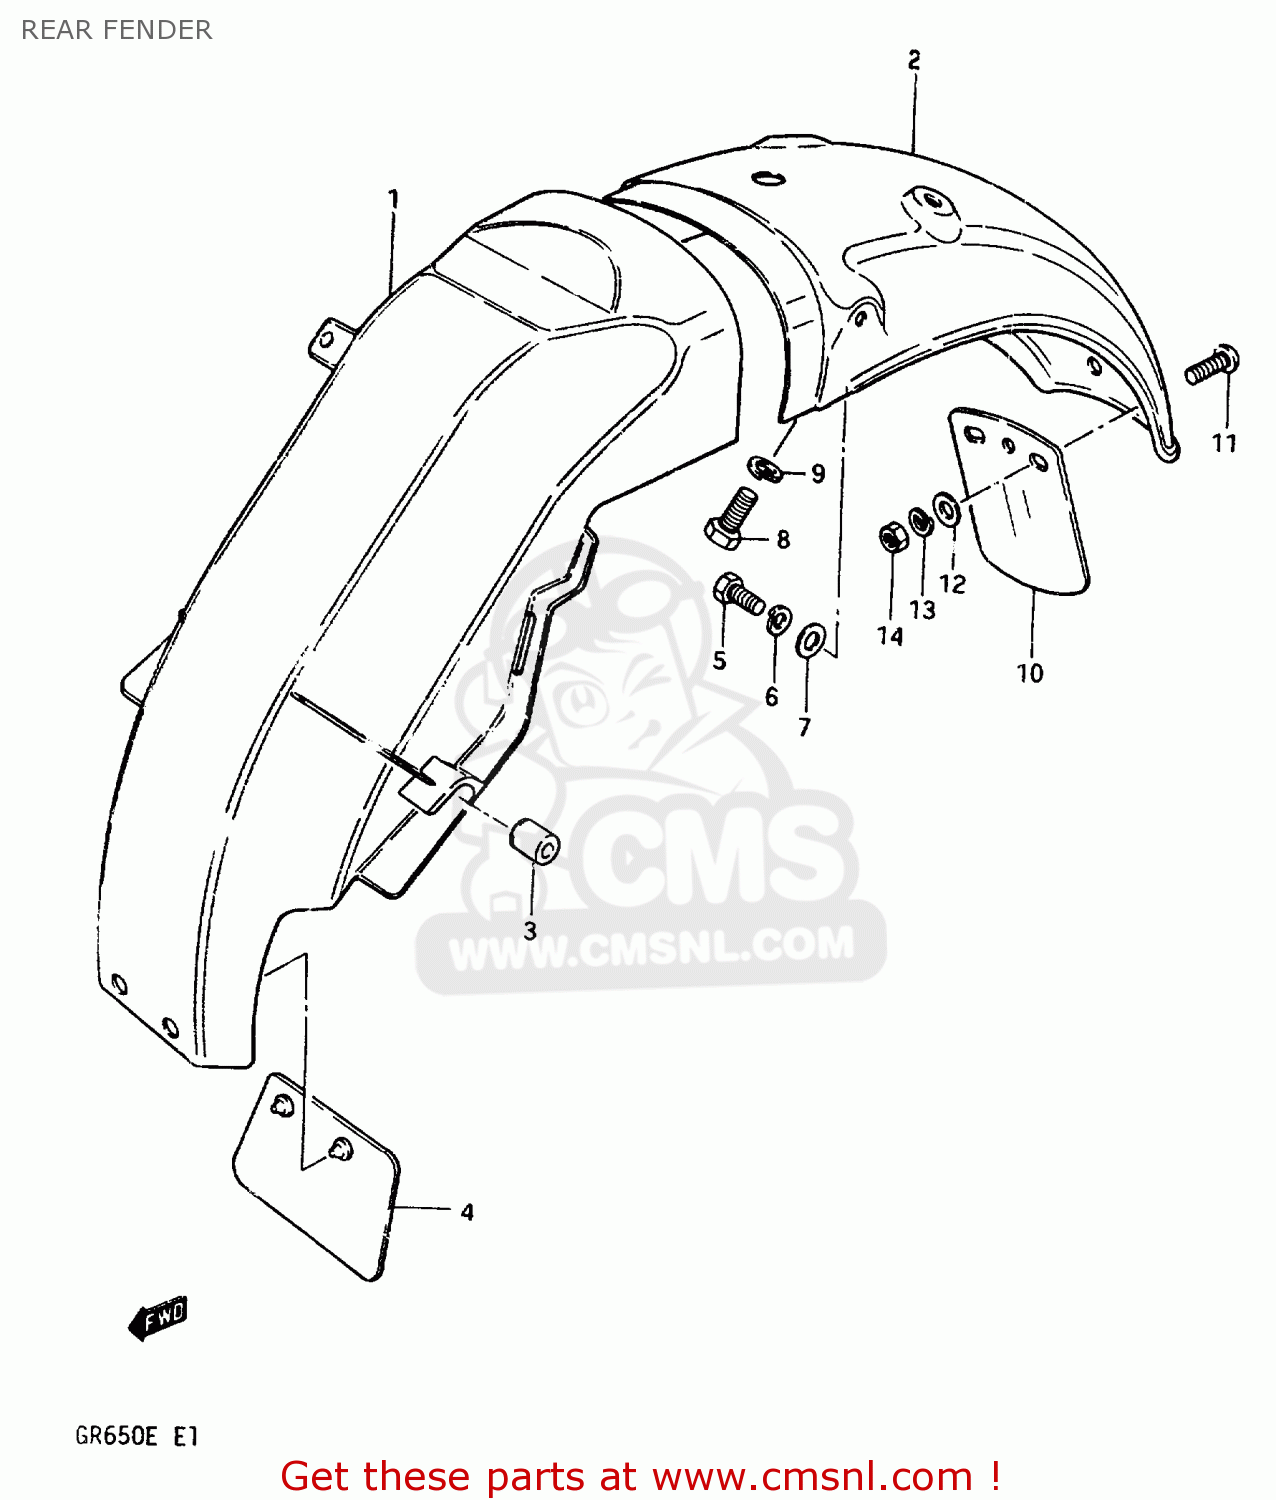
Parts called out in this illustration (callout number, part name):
1	BODY,REAR FENDER,FRONT
2	FENDER, REAR
3	CUSHION
4	GUIDE,RR FENDER MUD
5	BOLT, UPPER
6	LOCK WASHER
7	WASHER
8	BOLT
9	LOCK WASHER
10	FLAP,RR FENDER MUD
11	SCREW
12	WASHER
13	LOCK WASHER
14	NUT
